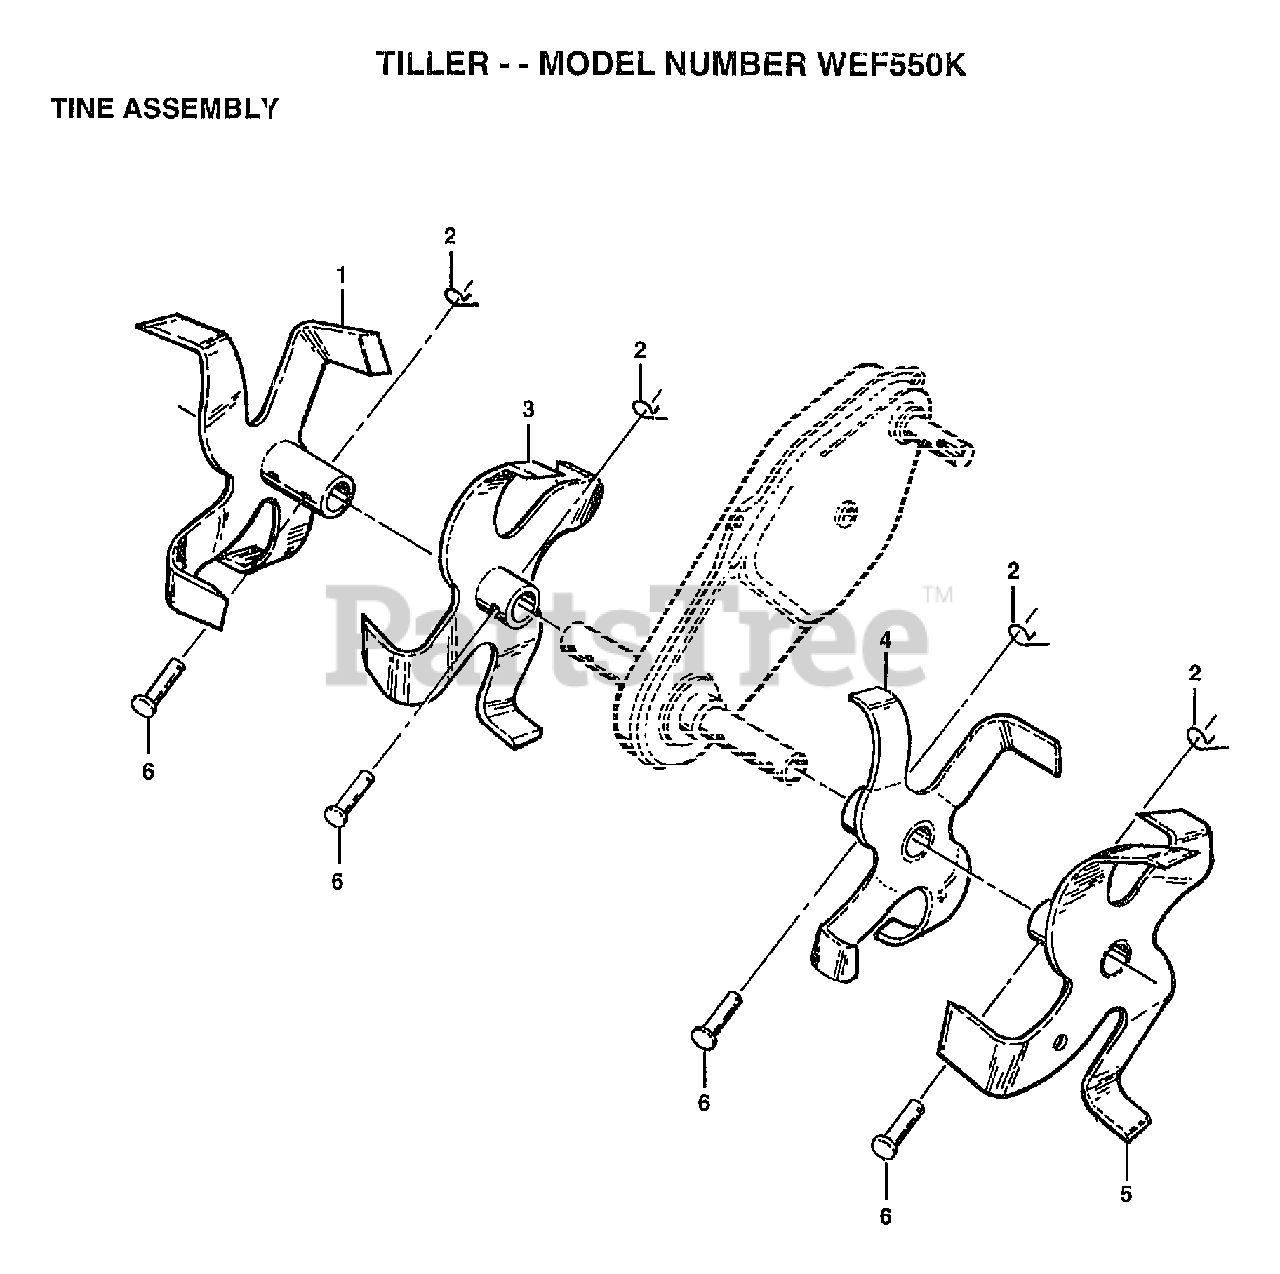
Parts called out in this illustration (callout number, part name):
1	"TINE ASM OUTER,RH"
2	RETAINER.SPRING
3	"TINE ASM INNER,RH"
4	TINE ASM INNER LH
5	"TINE ASM OUTER,LH"
6	RIVET.PAN HD.1.75
